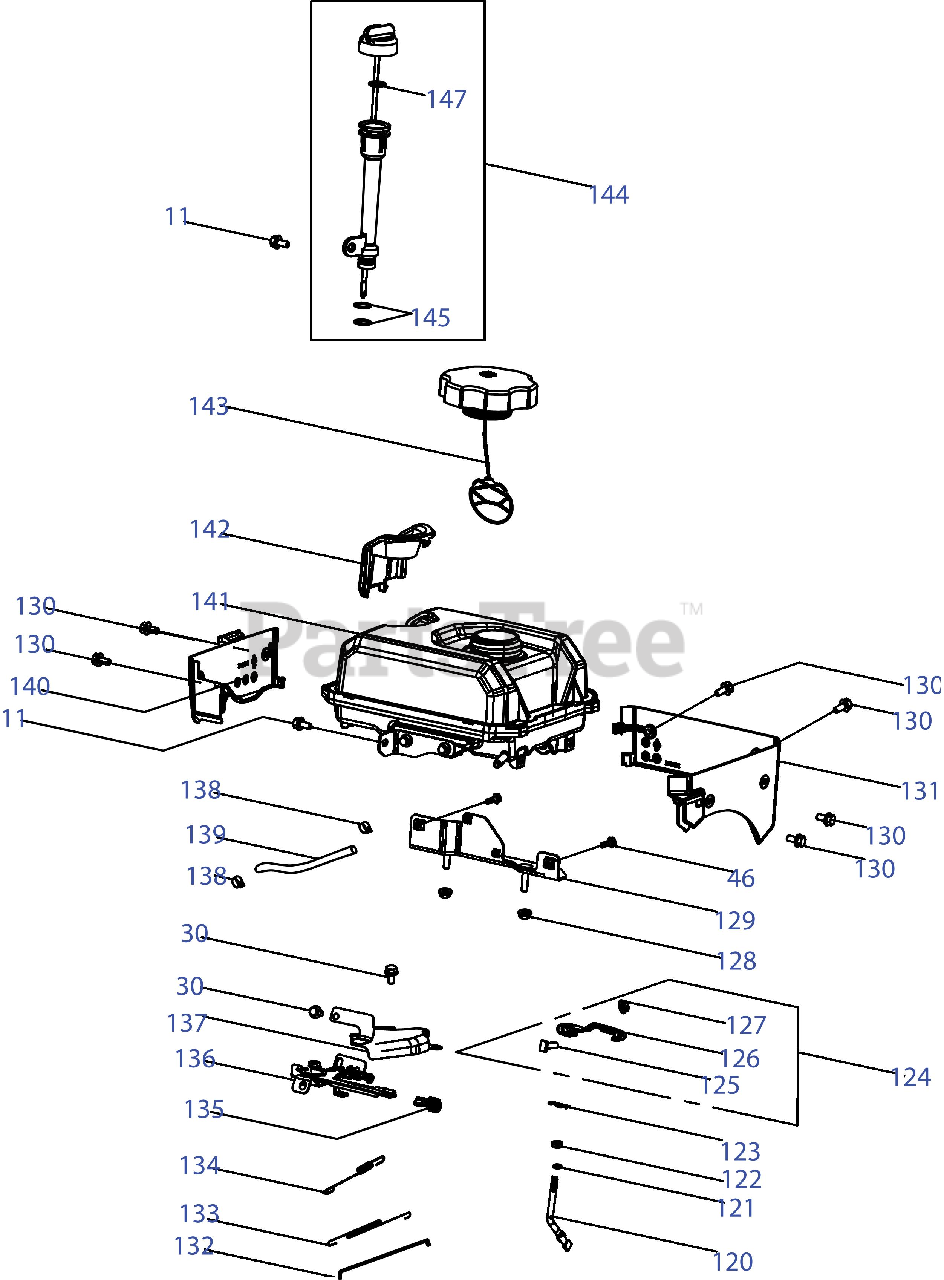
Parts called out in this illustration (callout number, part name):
11	Bolt, M6x12
30	Bolt, M6x12
46	Bolt, M6x18
120	Governor Gear Shaft
121	O-Ring, 5.2x1.9
122	Oil Seal, 6x11x4
123	Cotter Pin
124	Governor Lever
125	Bolt, M6x21
126	Governor Lever
129	Fuel Tank Bracket
130	Bolt, M5x14
131	Decorative Sheet, Left
132	Throttle Linkage
133	Idle Spring
134	Governor Spring
135	Throttle Lever Knob
136	Governor Gear Bracket Assembly
137	Governor Shield
138	Clamp
139	Fuel Hose, 6.3x12.5x162
140	Decorative Sheet, Right
142	Decorative Cover
145	O-Ring, 15.2x1.5
146	Dipstick Cover
147	O-Ring, 21x2.77
